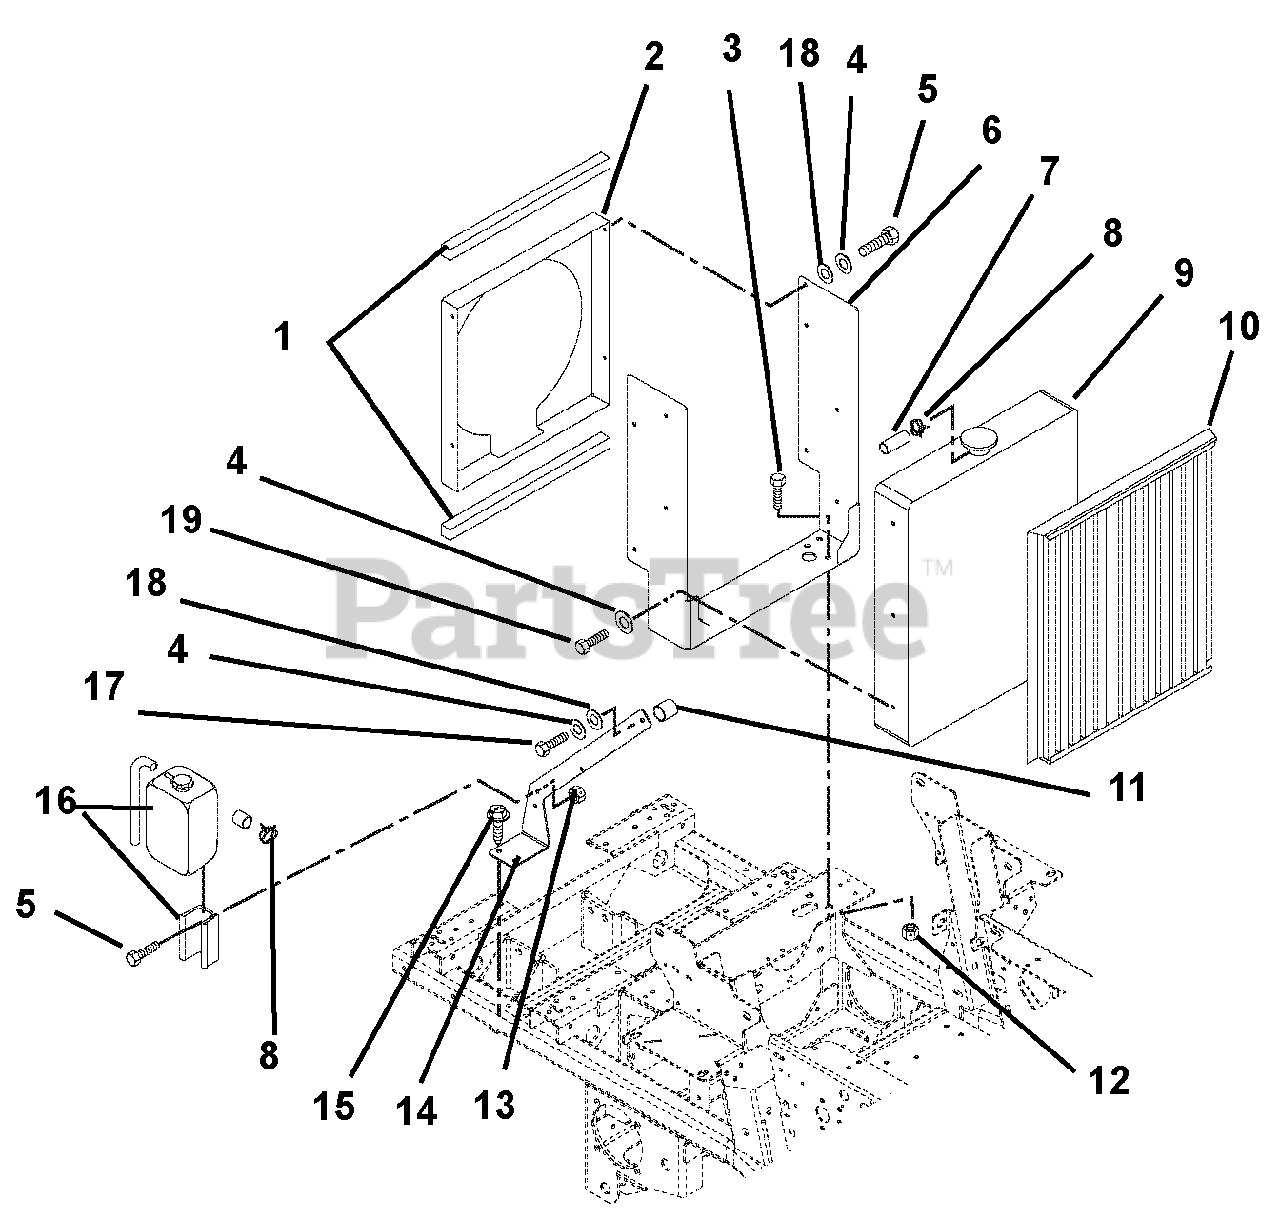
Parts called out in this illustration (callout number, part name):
1	SEAL, TRIM-LOK BULK .06 BBL 1'
2	WMT, RADIATOR SHROUD
3	@BLT-HEX .38-16X1.00 GR5 YWZC
4	@WSHR-LK .25X.062 REG YWZC
5	@BLT-HEX .25-20X.75 GR5 YWZC
6	WMT, RADIATOR MOUNTING BKRT
7	GAS LINE-BULK 1/4" I.D.
8	CLAMP-HOSE WIRE .490/.510X.116
9	Radiator (Comes with the engine)
10	SCREEN, RADIATOR (DIESEL)
11	SPACER .328 X .76 X 1.01
12	@NUT-LK-TOP-FLG .38-16 YWZC
13	@NUT-LK-TOP-FLG .25-20 YWZC
14	BRKT, OVERFLOW MOUNTING - BLK
15	@SCR-TAP .38-16X.75 HWH TR YWZ
16	Reservior Overflow (Comes with the engine)
17	@BLT-HEX M6-1.00X45 YWZC
18	@WSHR-FL-STL.281X.62X.065 YWZC
19	@BLT-HEX M6-1X16 YWZC
